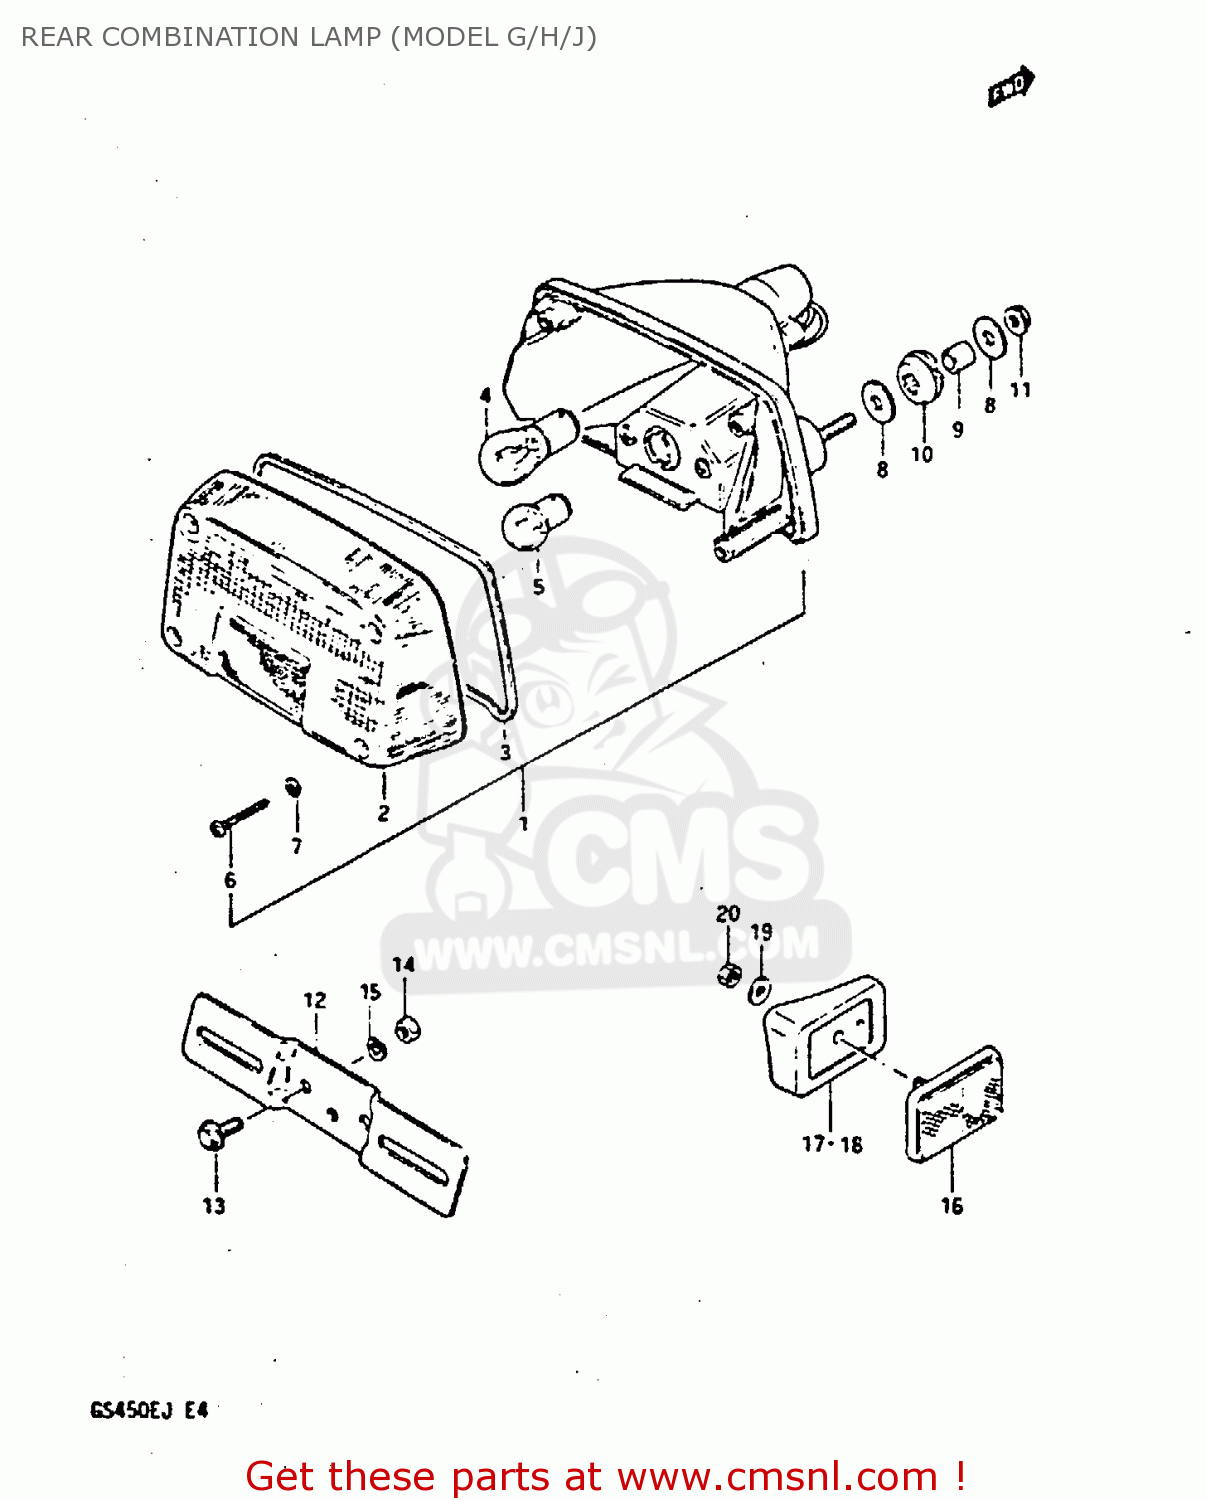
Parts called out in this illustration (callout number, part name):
1	LAMP ASSY, REAR COMBINATION
2	LENS
3	GASKET
4	BULB(12V23W)
5	BULB
6	SCREW
7	GASKET (NAS)
8	WASHER
9	SPACER (6.8X10X11.5)
10	CUSHION
11	NUT
12	BRACKET, LICENSE PLATE
13	BOLT
14	NUT
15	WASHER,LOCK
16	REFLEX REFLECTOR, REAR SIDE (RR018Y)
17	SPACER, RH
18	SPACER, LH
19	WASHER
20	NUT
